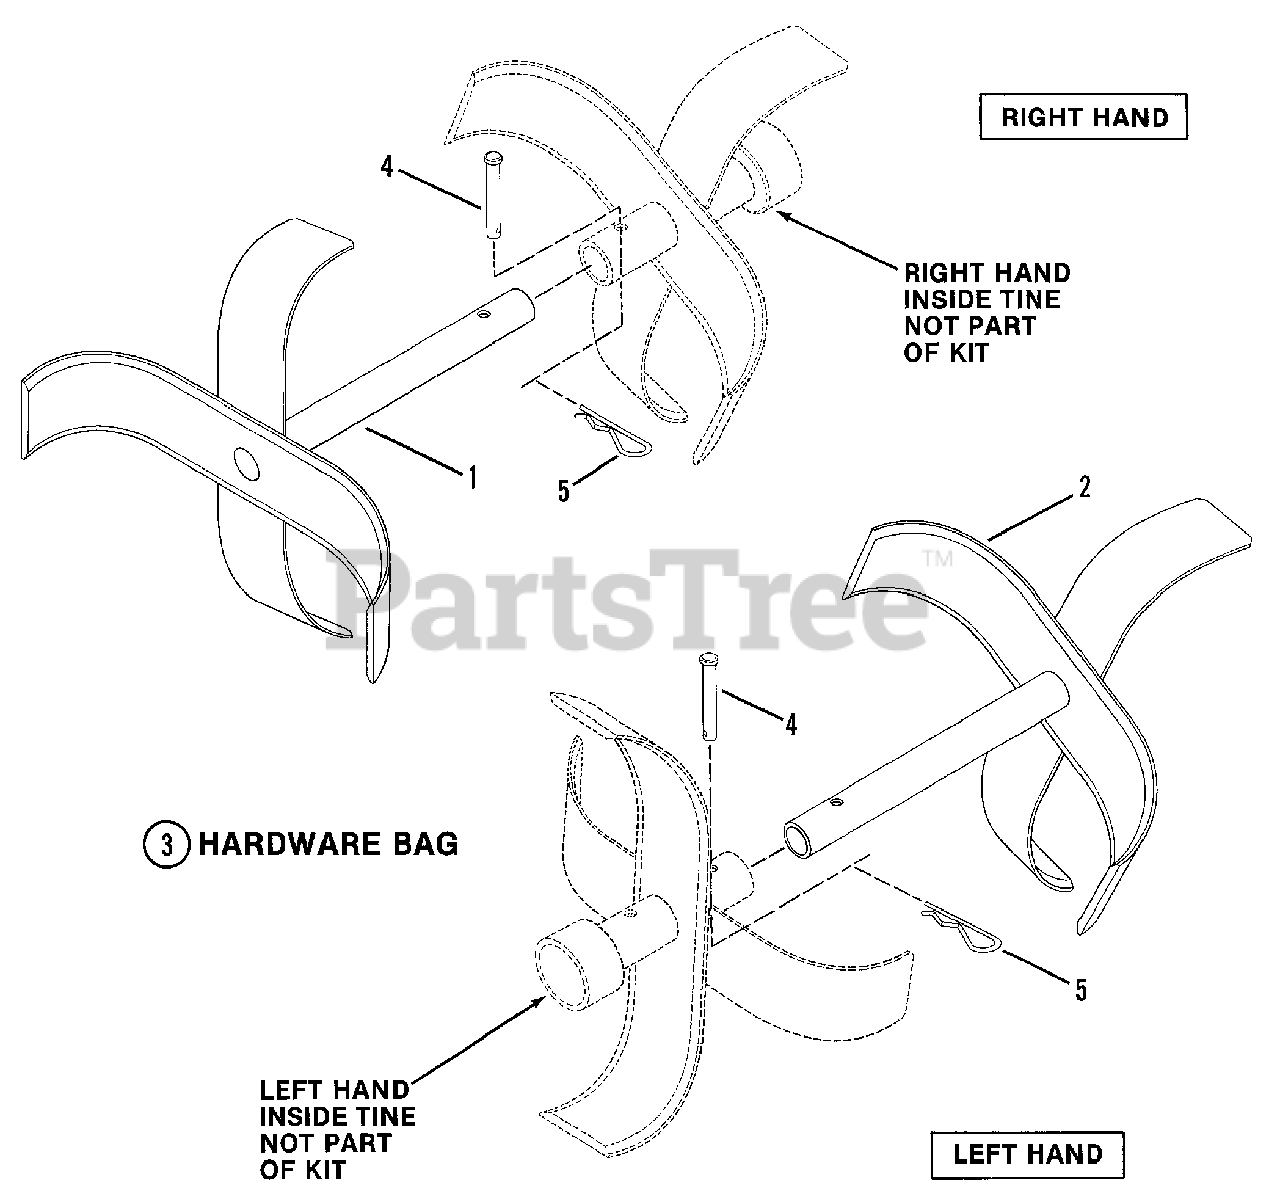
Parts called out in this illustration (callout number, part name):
1	(NLA) TINE EXTENSION, Right Hand
2	(NLA) TINE EXTENSION, Left Hand
4	PIN, 3/8 x 2-1/4" Clevis
5	PIN, Hair 2.25 x .093
